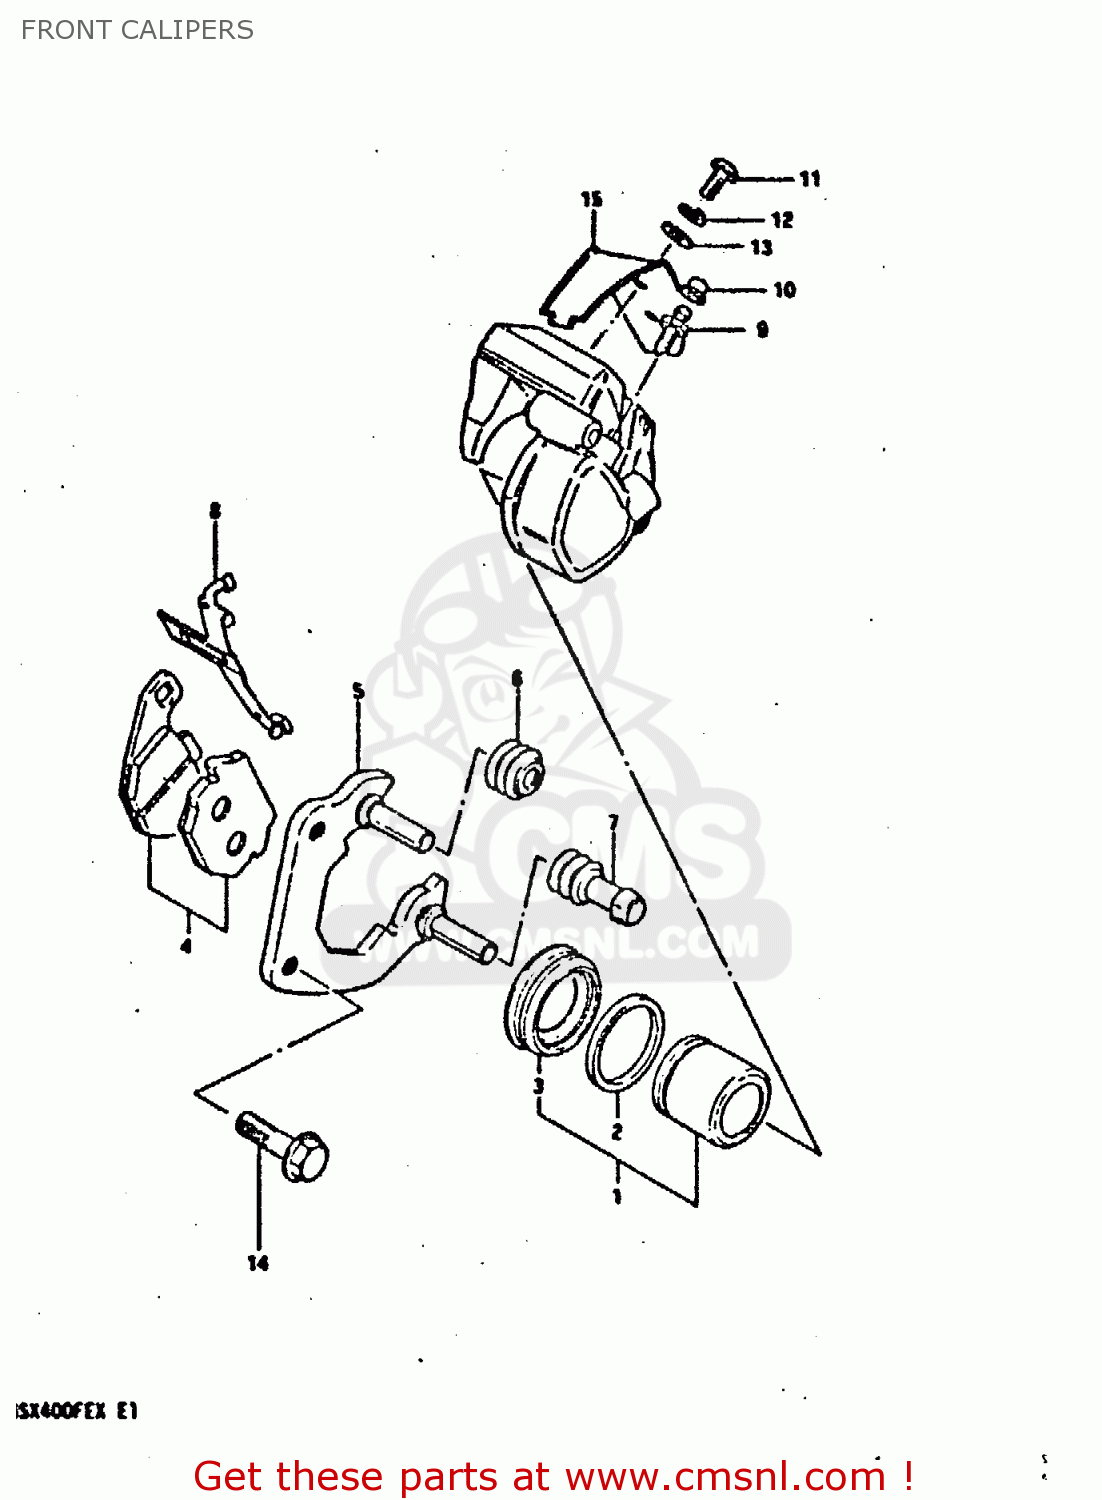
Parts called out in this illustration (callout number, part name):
1	PISTON SET
2	SEAL,PISTON
3	BOOT,PISTON
4	PAD SET, RH
5	CARRIER,CALIPE
6	BOOT,AXLE
7	INSULATOR,AXLE
8	SPRING,PAD
9	BLEEDER
10	CAP,BREATHER
11	SCREW
12	LOCK WASHER
13	WASHER
14	BOLT
15	COVER
